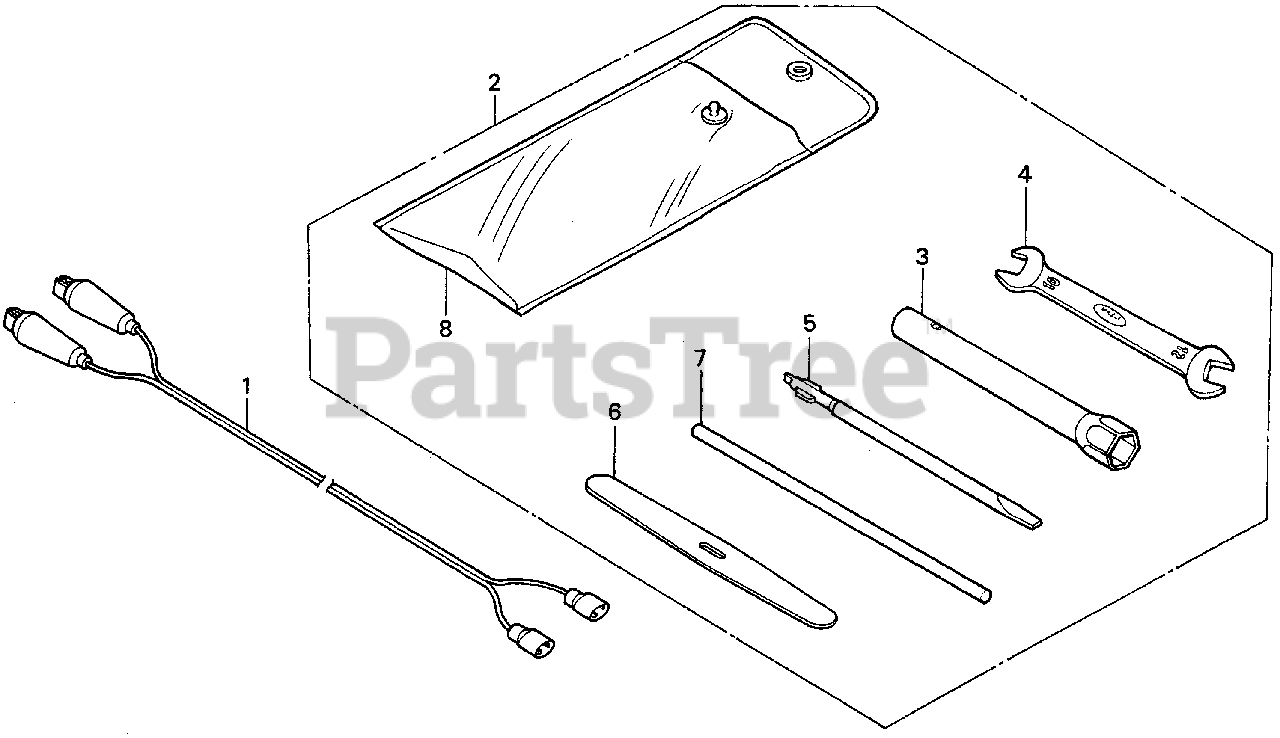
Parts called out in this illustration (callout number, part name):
1	WIRE ASSY., CHARGE
2	TOOL KIT (NOT AVAILABLE)
3	WRENCH, SPARK PLUG
4	SPANNER (10X12)
5	DRIVER 3, MINUS SCREW (NO.2)
7	BAR A, HANDLE
8	BAG, TOOL (230MM)
